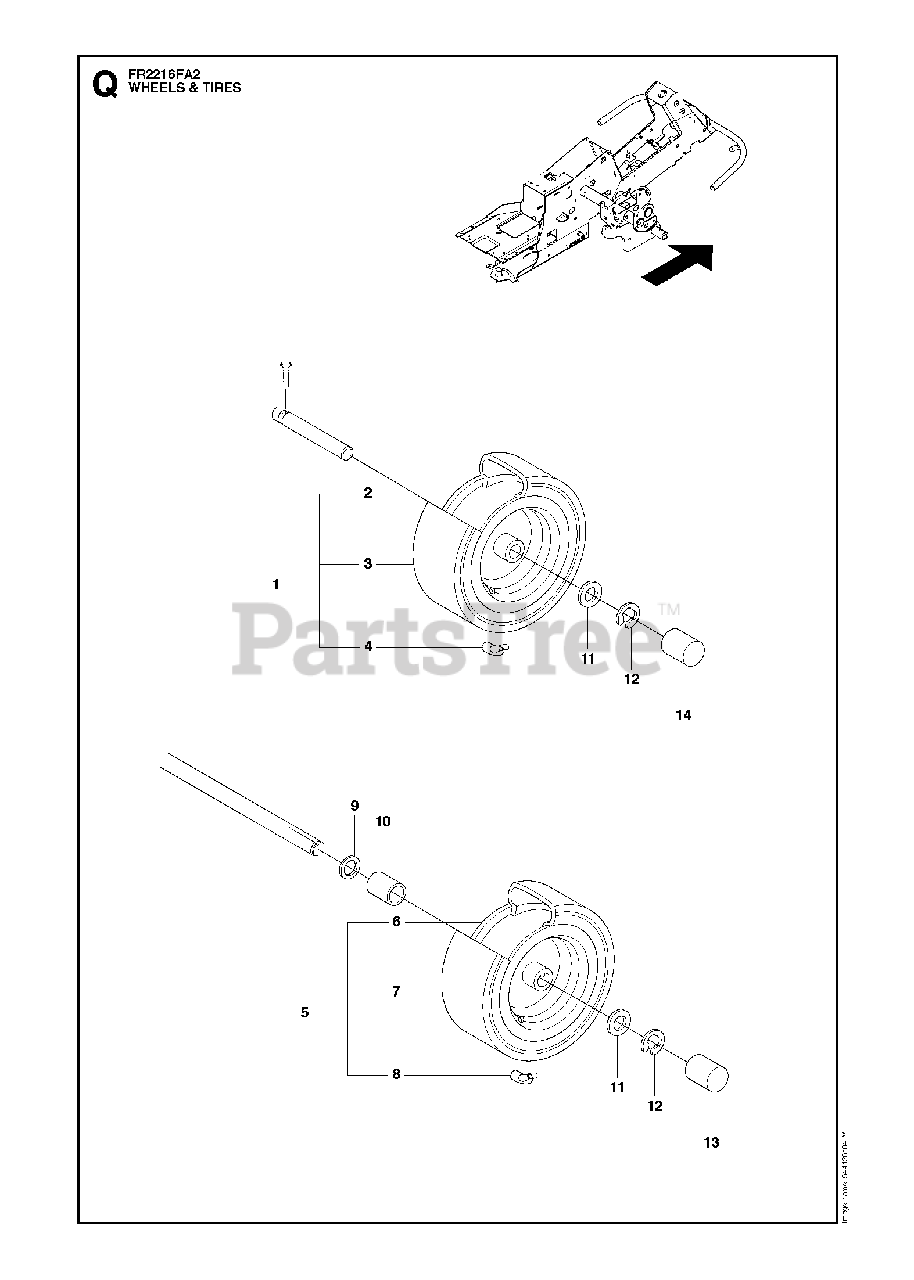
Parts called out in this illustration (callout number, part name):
10	SPACE SLEEVE
12	RETAINING RING
13	DUST CAP
